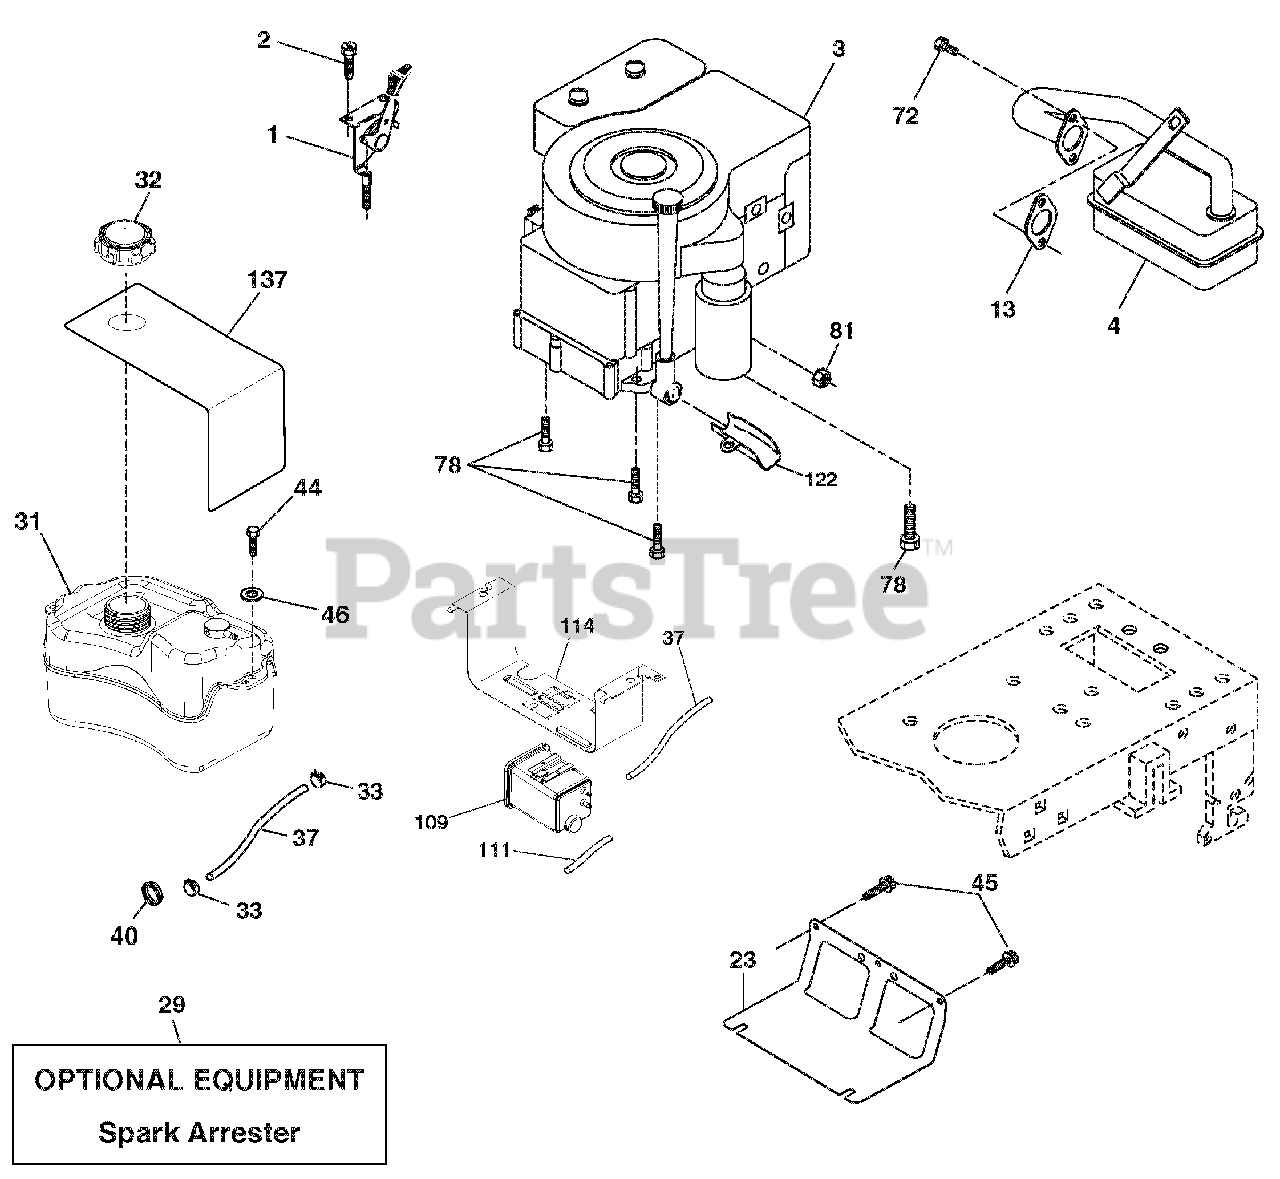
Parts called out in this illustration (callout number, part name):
1	Control Th/ch Flag
2	Screw 1/4-20 x 1/2
3	ENGINE, B&S 31C707-4346-G5(440007) (ORDER PARTS FROM ENGINE MANUFACTURER.)
4	Muffler Exhaust B&S
13	Gasket Eng 1 313 Id Tin Plated
23	Shield BRN/DBR Guard
29	KIT.SPARK ARRESTOR(392390 B&S)
31	TANK ASM.FUEL.1.50.CARB.CA.SVC
32	CAP FUEL
33	CLAMP.HOSE.BLK.
37	LINE.FUEL.22"FRONT.EMIS.CA.LP
40	Bushing Snap Nyl Blk Fuel Line
44	SCREW.HEXWSH.THDROL.1/4-20X3/4
45	SCREW.HEXWSH THDR3/8-16X3/4.BL
46	WASHER.9/32 X 7/8 X 16GA.
72	SCREW.SOCKET HD.5/16-18 X .75
78	Screw 3/8-16 x <
81	Nut, Keps Hex 1/4-20 unc
109	CANISTER.CARBON.FILTER ASM.TEX
111	PURGE.LINE.CARB
114	CRADLE.CANISTER.CARBON
122	Extension Drain Oil
